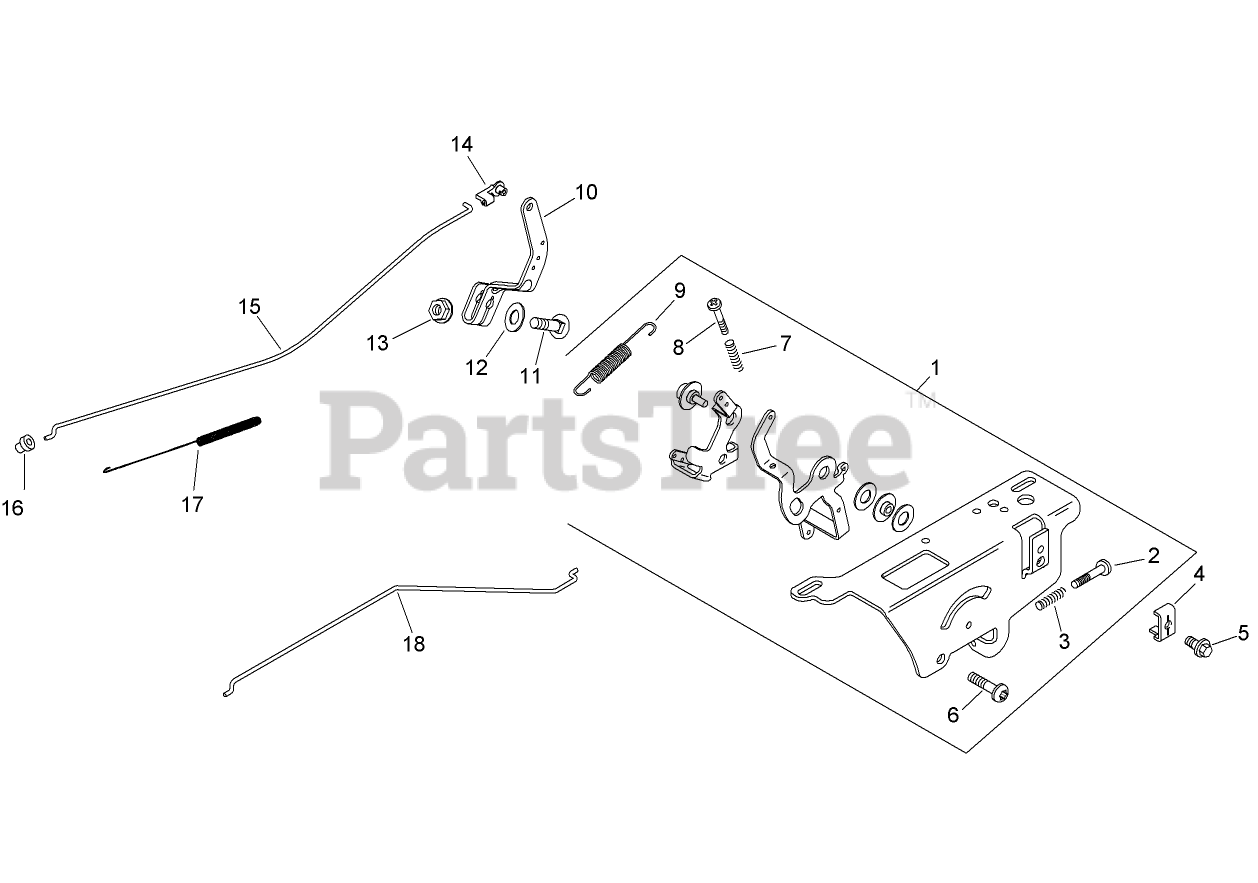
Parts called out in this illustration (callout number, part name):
1	Speed Control ASM
2	Screw-Thread Forming (M4x0.7x25)
2	SCREW-PHL THD FRM (M4X0.7X38)
3	Spring-Control, Speed
3	SPRING-CONTROL, SPEED (LONG)
4	CLAMP-CABLE
5	SCREW-FLANGE, THREAD FORMING (M5X0.8X16)
6	Screw-Socket, 6 Lobed (Thread Forming, M6x1.0x20)
7	Screw-Thread Forming (M4x0.7x25)
8	SCREW-PHL THD FRM (M4X0.7X38)
9	Spring-Governor
10	Lever-Governor
11	Bolt-Square Neck, Round Head (1/4-20x1)
12	Washer-Lock, Internal Tooth (1/4)
13	Nut-Flange, Hex (1/4-20)
14	BUSHING-RETAINING, LINKAGE
15	Linkage-Throttle
16	BUSHING-LINKAGE, THROTTLE
17	Spring-Linkage
18	Linkage-Choke (Single Wire)
